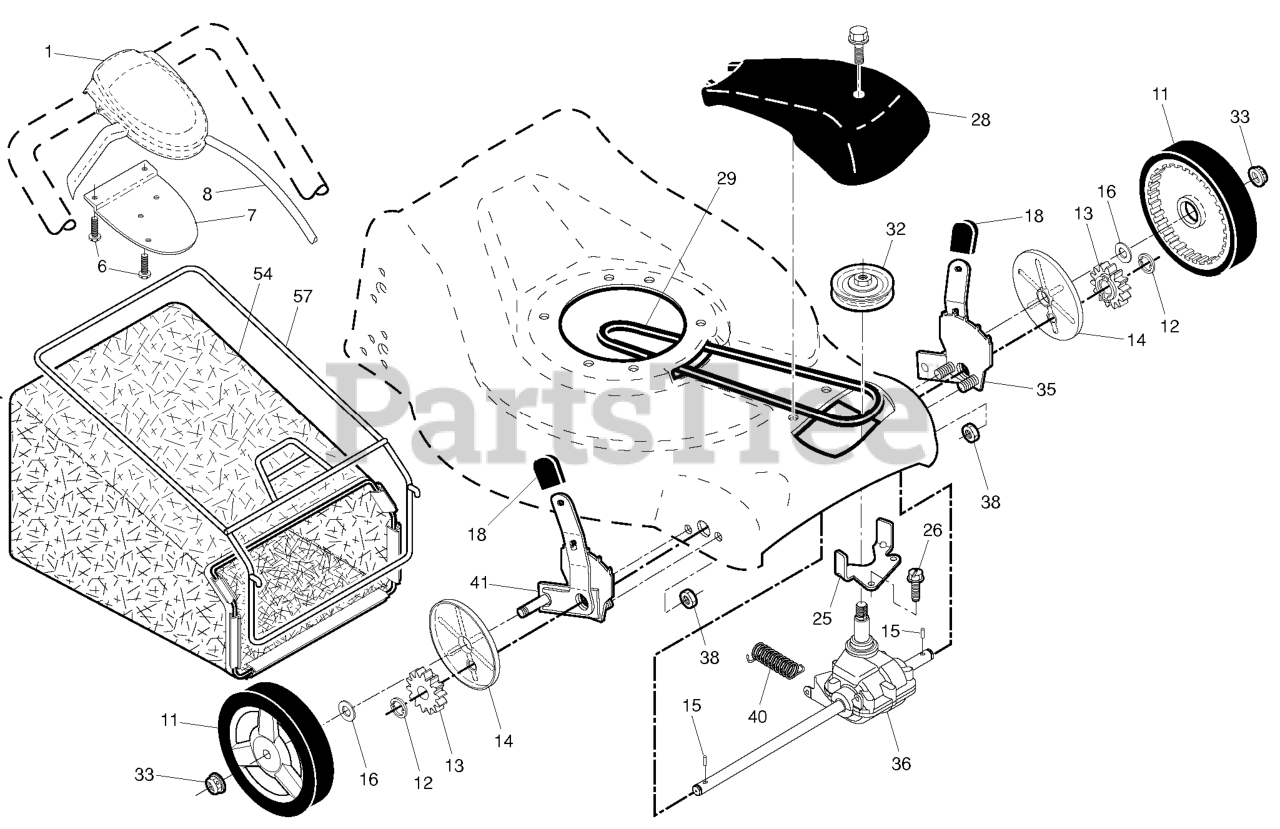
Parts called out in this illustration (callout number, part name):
1	CONTROL.DR.QW.21FGD.BS.GY/BLK
6	SCREW, PHILLIPS HEAD 10 X 5/8
7	BRACKET.DRIVE.CONTROL.MOUNT.BL
8	CABLE ASSEMBLY, DRIVE
11	WHEEL.8X1.75.H3SPK.RAD3.GY.BU3
12	E-RING 7/16 RE
13	PINION.14.TEETH.FGD
14	COVER.DUST.WHEEL.INNER.WALK
15	PAWL, DRIVE
16	WASHER FLUT
18	SELECTOR KNOB
25	BRACKET.BELT.GUIDE.22+FGD.BZP
28	COVER.DRIVE.ASM.185579.CE.WALK
29	BELT.DRIVE.FG
32	RP PULLEY.DRIVE.EZ/VAR.SCREWON
33	NUT.HEX.FLANGE.3/8-16.LO(3 2)
35	KIT ADJUSTER ASM.438151.
36	TRANSMISSION.21.FGD.HT.VST
38	LOCKNUT.NYLOC.1/4-20
41	KIT ADJUSTER ASM.438148
54	GBAG.34710090.H-GREY MS498
57	FRAME.GBAG.21.FWGD
